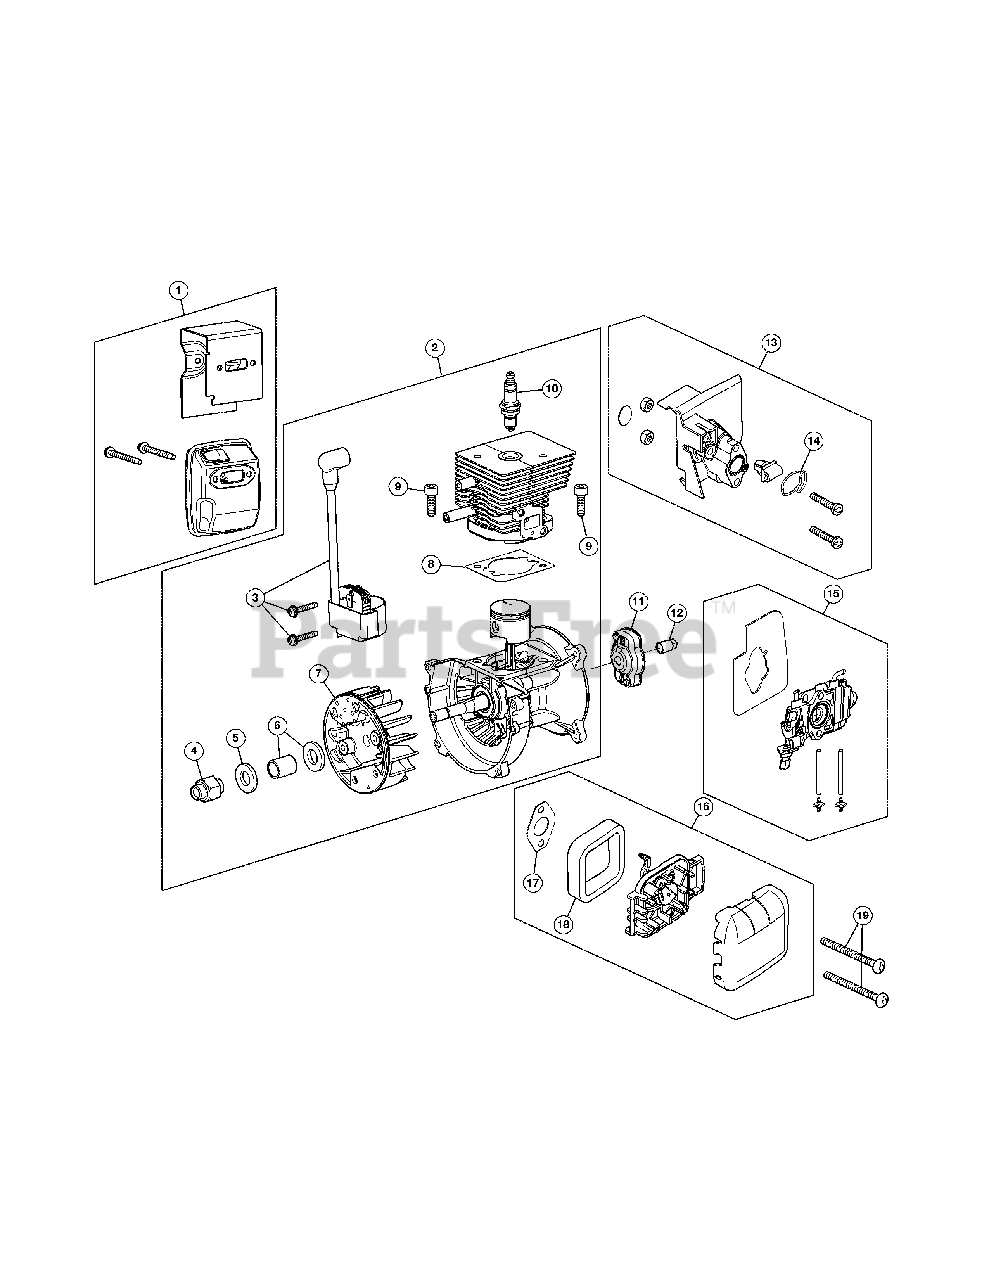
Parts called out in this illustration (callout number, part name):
1	Muffler Assembly
2	Shortblock Assembly (Incl. 3 - 10)
3	Module Assembly
4	Flywheel Adaptor
5	Washer
7	Flywheel Assembly
8	Cylinder Gasket
10	Spark Plug
11	Pawl Assembly
12	Electric Start Adaptor
13	Insulator Assembly (Incl. 14)
14	Insulator O-Ring
15	Carburetor Assembly
16	Air Cleaner Assembly (Incl. 17 and 18)
17	Carburetor Gasket
19	Air Cleaner Screw
